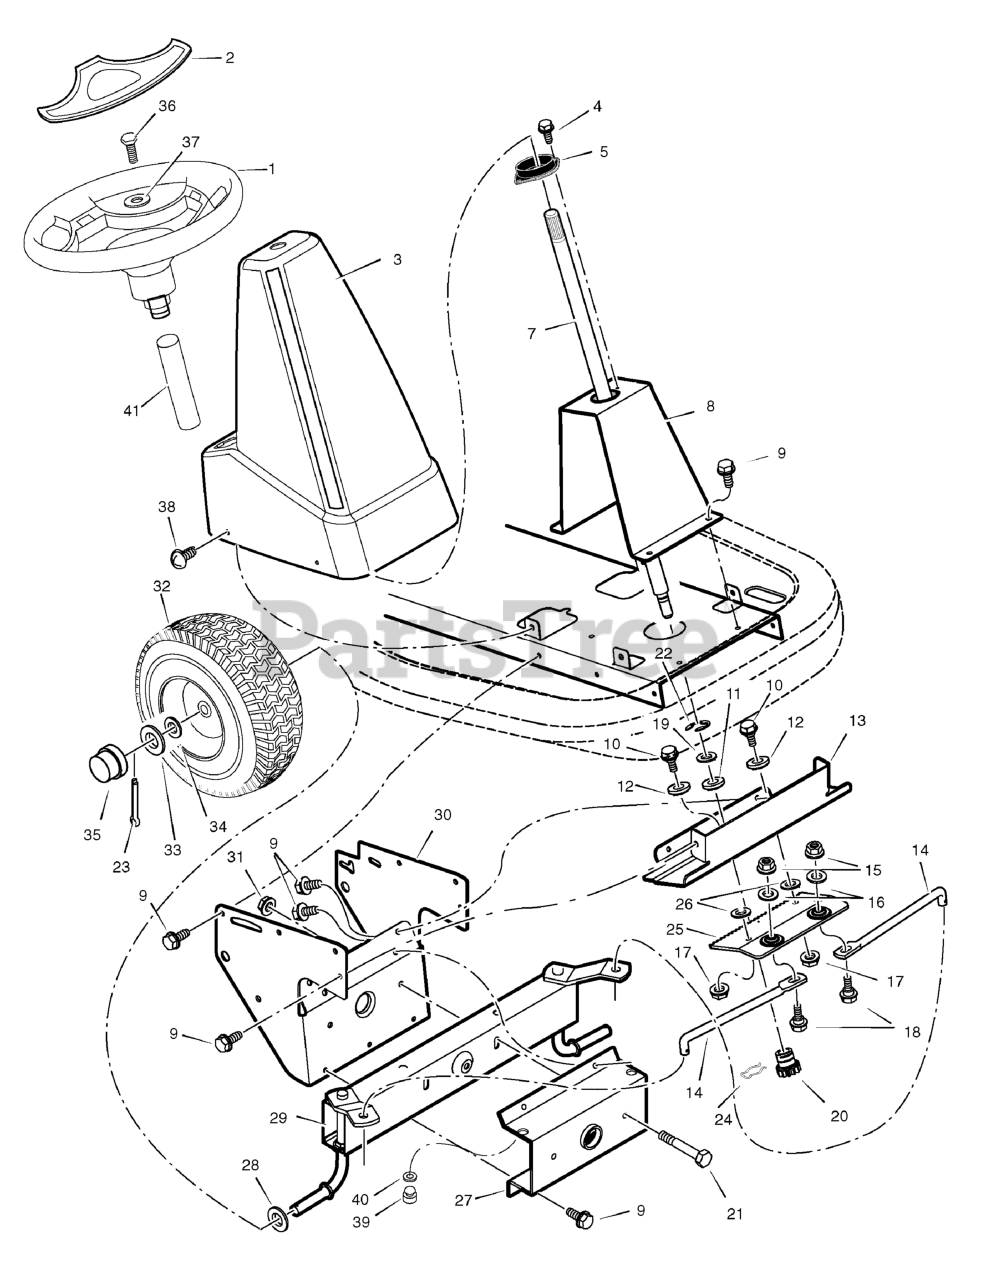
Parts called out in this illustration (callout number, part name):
1	WHEEL, Steering
2	Cap, Steering
3	CONSOLE, Low
4	SCREW
5	BEARING, Upper Steering
7	SHAFT, Steering
8	SUPPORT, Steering
10	BOLT, Shoulder
11	BEARING, Lower Steering
13	PLATE, Gear Mounting
15	NUT, Flange
17	NUT, Flange
18	BOLT, Hex
20	GEAR, Pinion
21	BOLT, Hex, 5/16-24 x 2-3/4
22	E-RING, Retainer
23	PIN, Cotter
24	RETAINER, Spring
25	RACK, Steering
27	BRACKET, Axle Front
29	AXLE & SPINDLE ASSEMBLY
30	BRACKET, Support
31	NUT, Flange
32	WHEEL, Front
35	Cap, Hub
36	SCREW, Hex
37	WASHER
